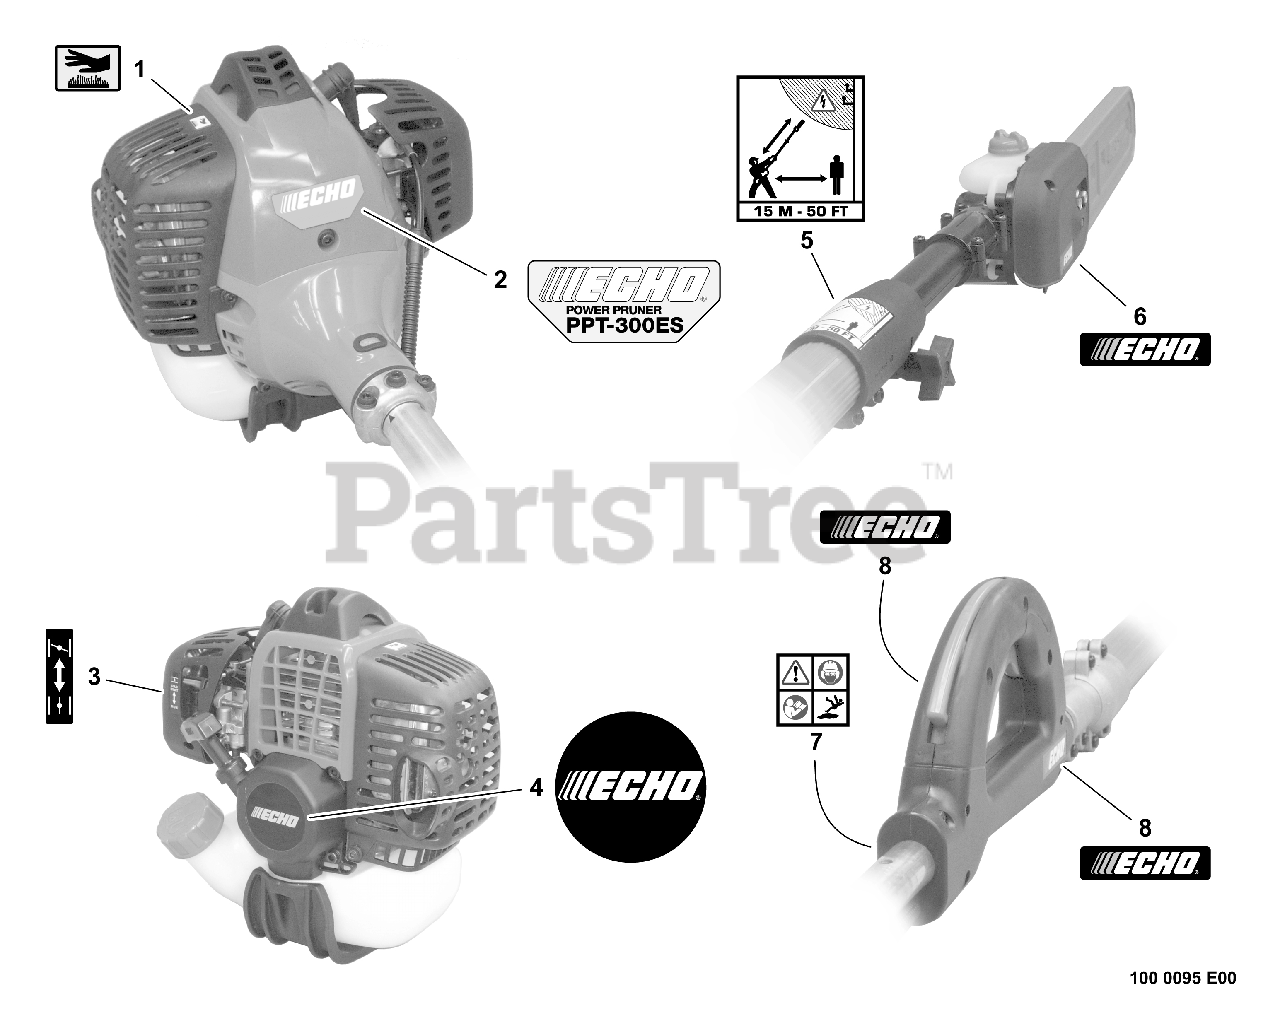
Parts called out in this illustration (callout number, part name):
1	LABEL - HOT SURFACE
2	LABEL - MODEL PPT-300ES
3	LABEL - CHOKE
4	LABEL - ECHO
5	LABEL - WARNING
6	LABEL - ECHO
7	LABEL - CAUTION
8	LABEL - ECHO
